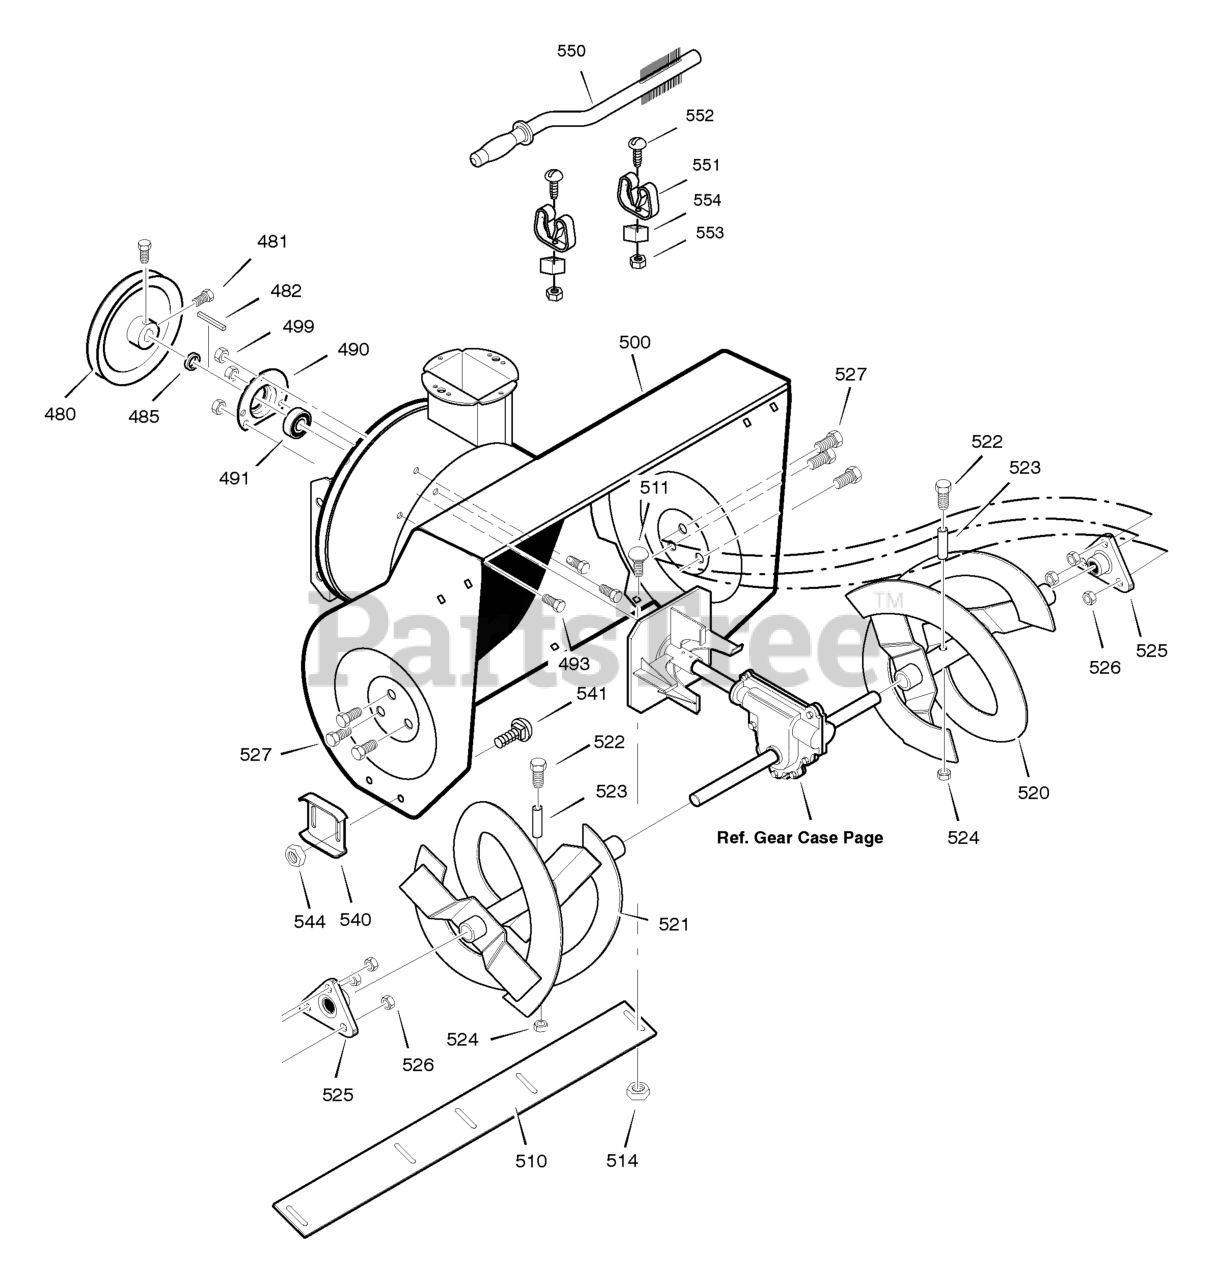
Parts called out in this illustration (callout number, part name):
480	PULLEY, 4L 6.12X .67
481	SCREW, 5/16-18 x 0.63
482	KEY, SQUARE 3/16 X 3/4
485	SPACER, FRICTION PULLEY
490	RETAINER, BALL BRNG
491	BEARING, BALL
493	BOLT, HEX 5/16-18X .50
499	NUT, 5/16-18 HEXWDFLLK
500	HOUSING, ASSY
510	BLADE, SCRAPER
511	BOLT, 1/4-20X.75
514	NUT, 1/4-20
520	AUGER, ASSY, LH
521	AUGER, ASSY, RH
522	SCREW, 1/4-20X1.75
523	SPACER, SLEEVE
524	NUT, 1/4-20
525	BEARING,FLANGE
526	NUT, 5/16-18
527	SCREW, 5/16-18 x 0.75
540	SKID, HEIGHT ADJUST
541	BOLT, 5/16-18 X .75
544	NUT, 5/16-18
550	BRUSH, CLEANOUT
551	CLIP, RETAINER
552	SCREW
553	NUT
